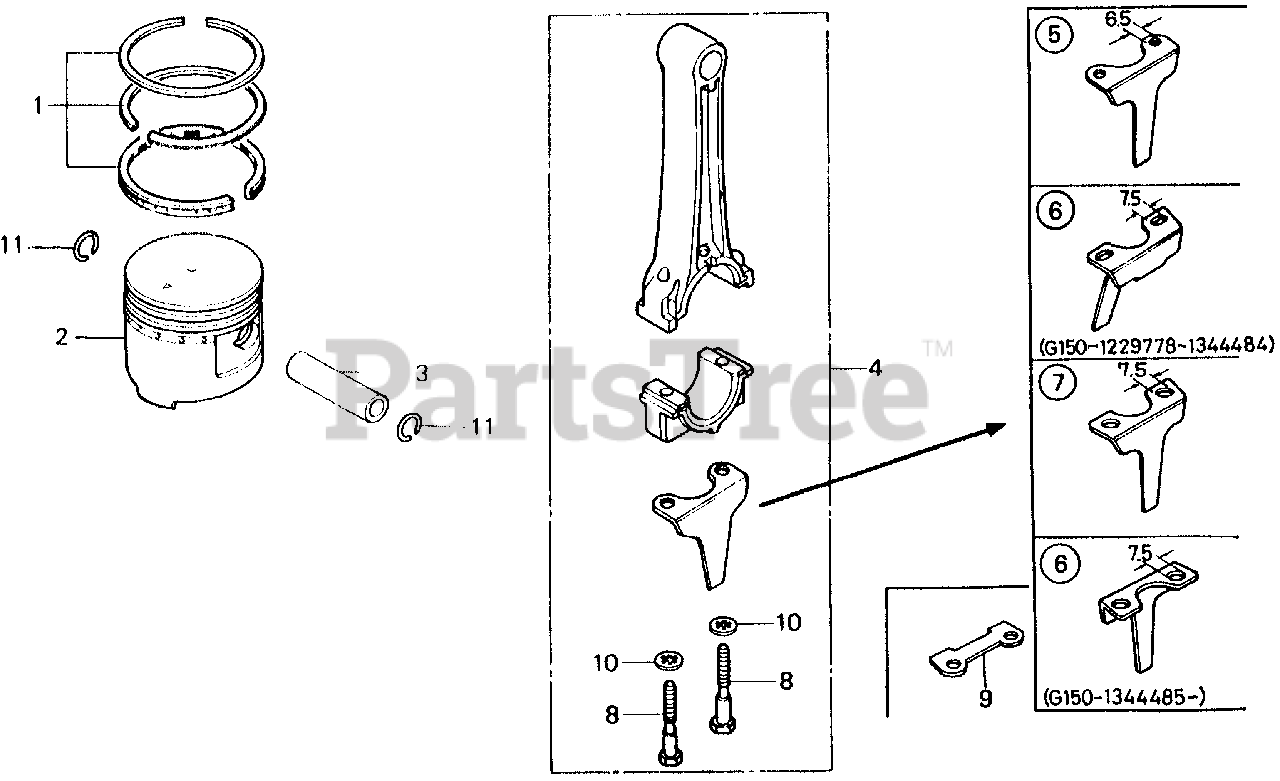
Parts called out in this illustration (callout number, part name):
1	RING SET, PISTON (STD)
1	RING SET, PISTON (OS 0.25) (OS)
1	RING SET, PISTON (OS 0.50) (OS)
1	RING SET, PISTON (0.75) (OS)
2	PISTON (STD)
2	PISTON (OS 0.25) (OS)
2	PISTON (OS 0.50) (OS)
2	PISTON (0.75) (OS)
3	PIN, PISTON
4	ROD ASSY., CONNECTING
4	ROD ASSY., CONNECTING (UNDER SIZE) Use up to Engine SN 1167848.
4	ROD ASSY., CONNECTING (US 0.25) Use from Engine SN 1229778.
4	ROD ASSY., CONNECTING (UNDER SIZE) Use up to Engine SN 1229777.
5	DIPPER, CONNECTING ROD (NOT AVAILABLE)
6	DIPPER, CONNECTING ROD
7	DIPPER, CONNECTING ROD (NOT AVAILABLE)
8	BOLT, CONNECTING ROD (6MM)
8	BOLT, CONNECTING ROD (6MM) (NOT AVAILABLE)
8	BOLT, CONNECTING ROD (7MM)
9	WASHER B, CONNECTING ROD
10	WASHER, LOCK (6MM) (N/A: SEE ASSEMBLY)
10	WASHER, LOCK (7MM)
11	CLIP, PISTON PIN (15MM)
